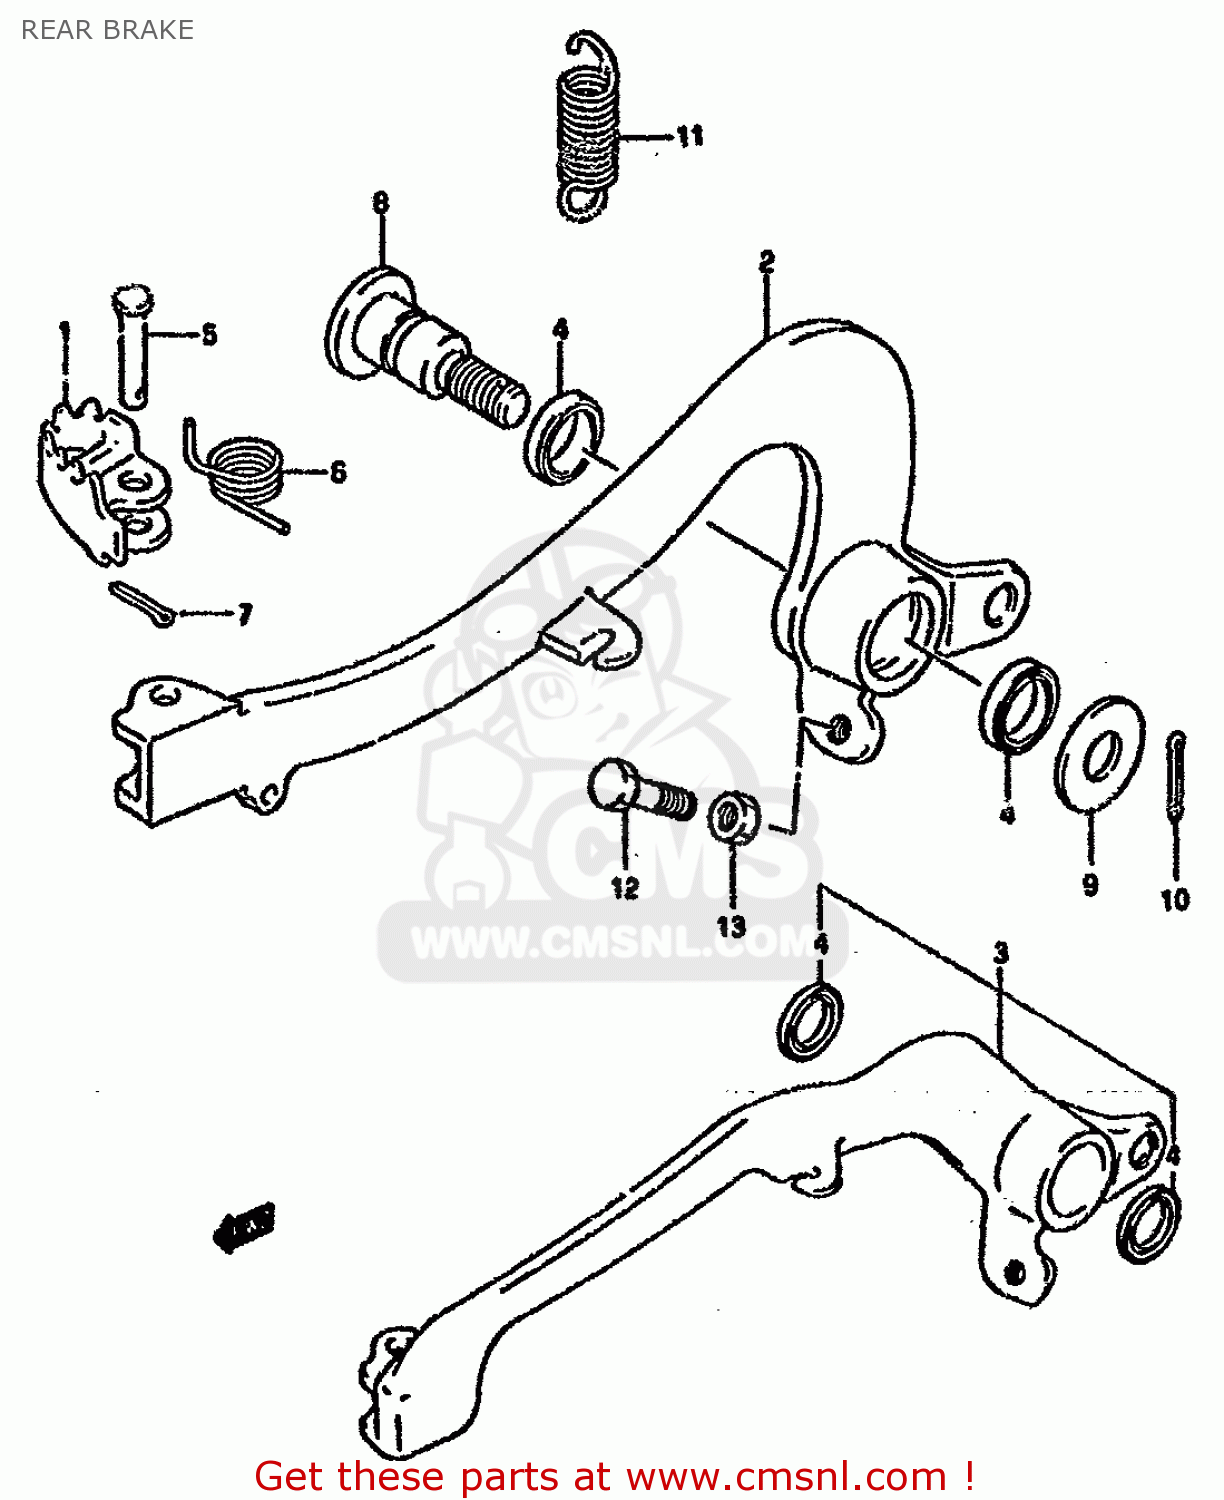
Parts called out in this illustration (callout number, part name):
1	PEDAL,BRAKE
2	ARM COMP,BRAKE PEDAL
3	ARM,BRAKE PEDAL
4	SEAL,OIL(15X21X3)
5	PIN(6X23.5)
6	SPRING
7	PIN
8	SHAFT,BRAKE PEDAL
9	WASHER
10	PIN 20X20
11	SPRING
12	BOLT(6X23)
13	NUT
